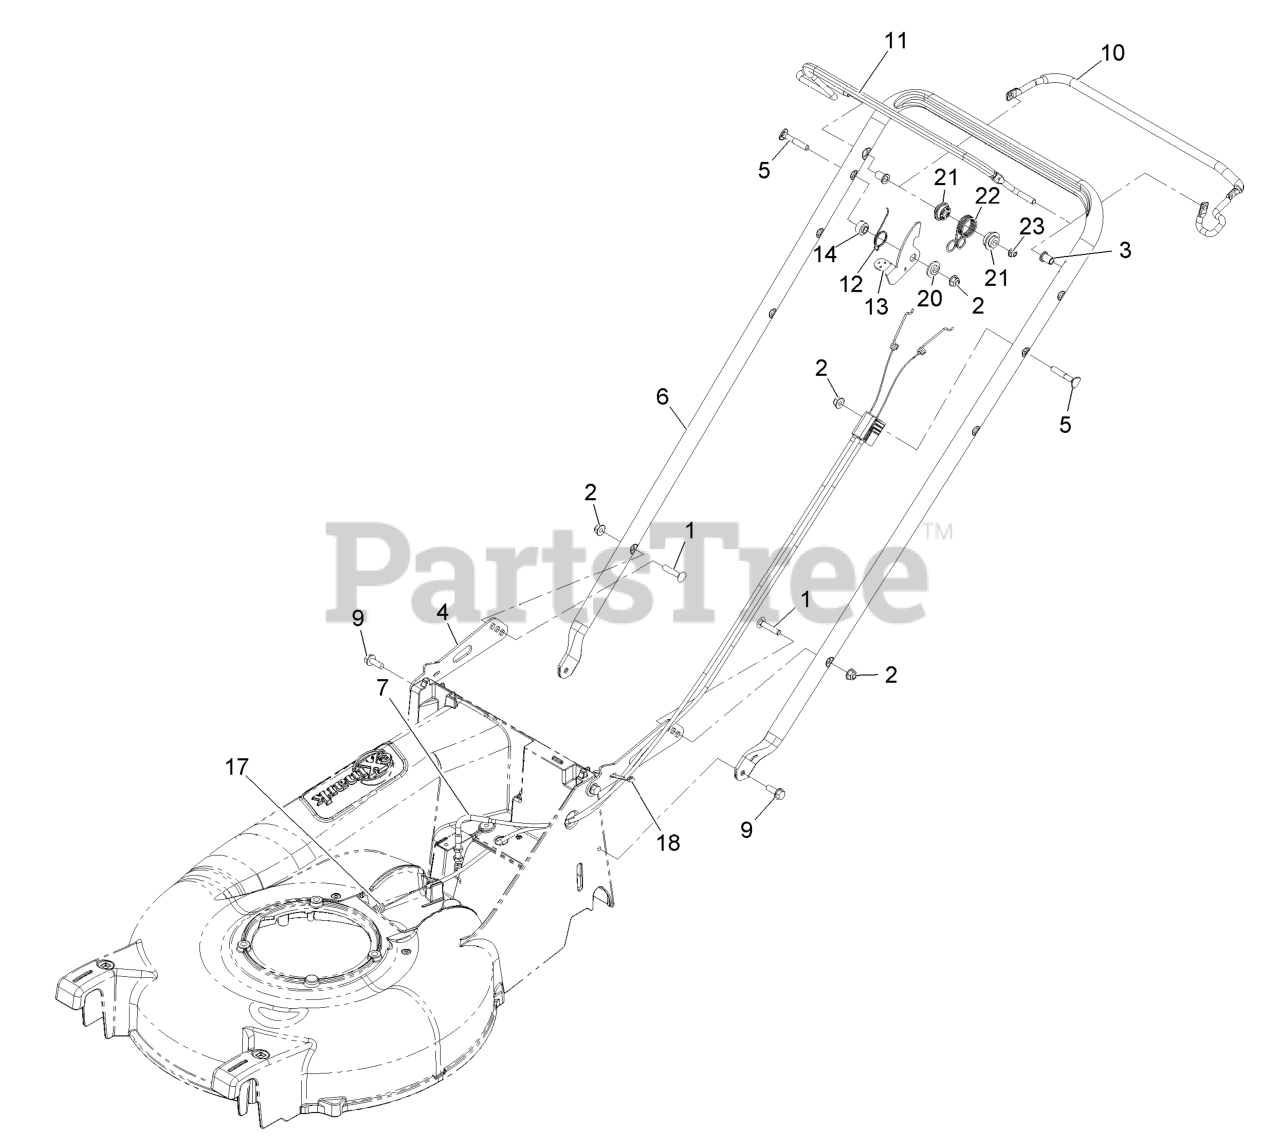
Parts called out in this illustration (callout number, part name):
1	BOLT-CARR
2	NUT-HF, NI
3	BUSHING-HANDLEBAR
4	BRACKET,HANDLEBAR
6	HANDLEBAR-P21
9	SCREW-TAPTITE
10	BAIL-DRIVE COATED
12	SPRING-LEVER, BBC
13	LEVER-BBC
14	BUSHING-STEPPED
17	CABLE-BBC
18	TIE-CABLE
20	WASHER-STEPPED
21	BUSHING-SPRING, PIVOT
22	SPRING,BBC RETURN
